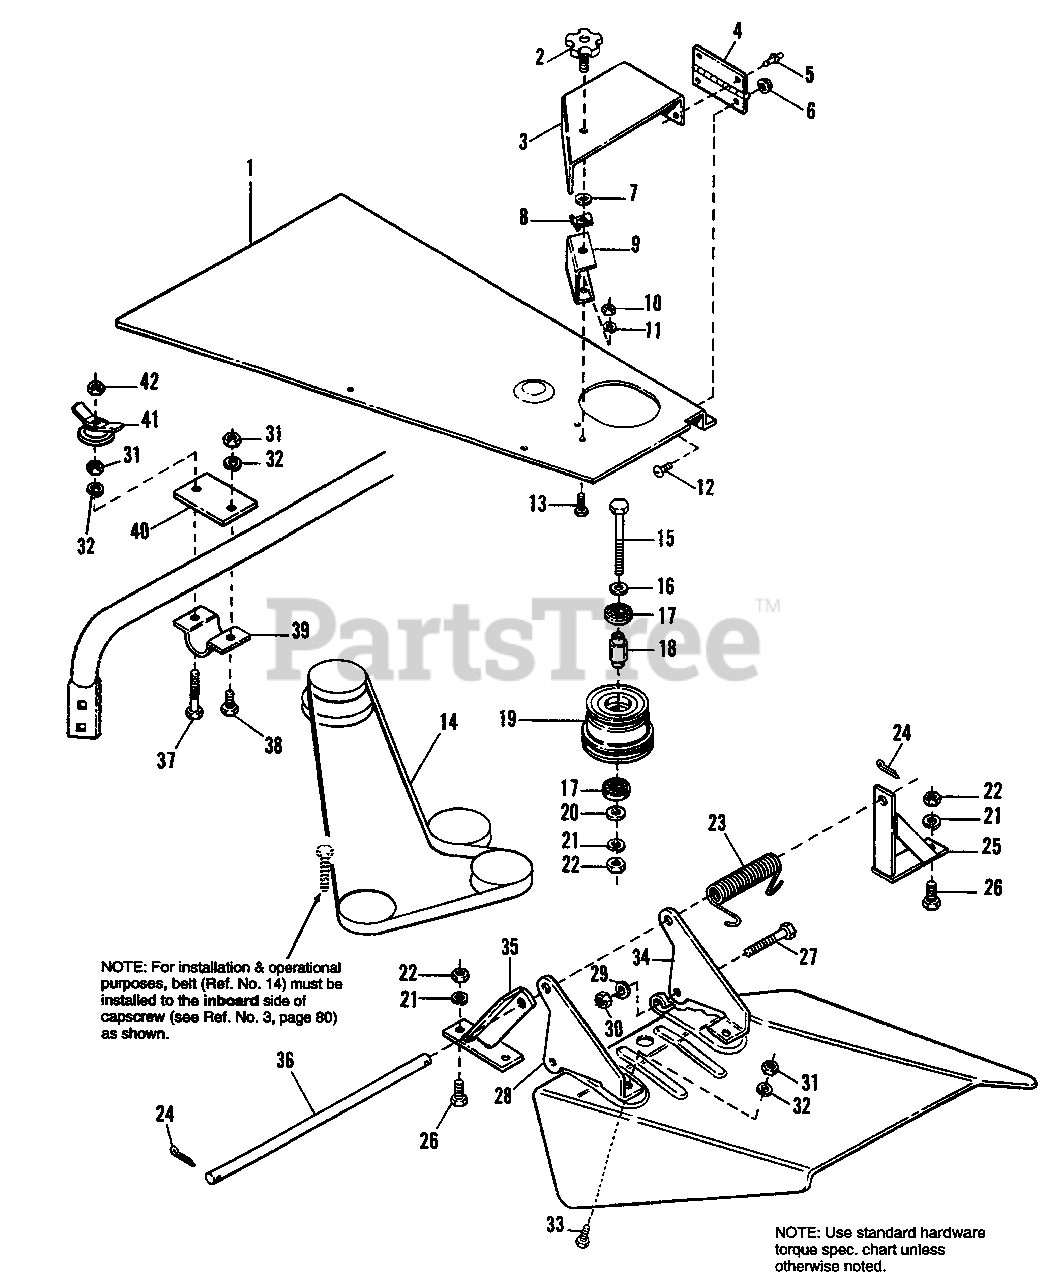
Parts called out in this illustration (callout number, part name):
1	COVER, L.H. Mower
2	PLASTIC KNOB
3	COVER ASSY.,
5	RIVET, 3/16 x 5/16
6	NUT, Hex, Washer #10-32
7	PUSH NUT, 5/16 Stud
8	PALNUT, 5/16-18
9	BRACKET, Belt Cover
10	NUT, Hex, Full, 1/4-20
11	LOCKWASHER, 1/4
12	SCREW, Rd. Hd., Mach., #10-32 x 3/8
13	CAPSCREW, Hex, 1/4-20 x 1/2
14	V-BELT
15	SCREW, Cap, Hex, 3/8-16 x 3-1/4
16	WASHER, Special
18	SPACER, Pulley
21	LOCKWASHER, 3/8
22	NUT, Hex, Full, 3/8-16
23	SPRING, Torsion
24	PIN, Cotter, 3/32 x 3/4
25	HINGE ASSY., Rear
26	CAPSCREW, Hex, 3/8-16 x 1
27	CAPSCREW, Hex, 7/16-14 x 2-1/4
28	PIVOT, Bracket, L.H.
29	LOCKWASHER, 7/16
30	NUT, Hex, Full, 7/16-14
31	NUT, Hex, Full, 5/16-18
32	LOCKWASHER, 5/16
33	CAPSCREW, Hex, 5/16-18 x 7/8
34	PIVOT, Bracket, R.H.
35	HINGE ASSY., Front
37	CAPSCREW, Hex, 5/16-18 x 2-1/2
38	CAPSCREW, Hex, 5/16-18 x 5/8
39	CLAMP, Lower
40	CLAMP, Upper
42	NUT, Hex, Full, Lock, 5/16-18
